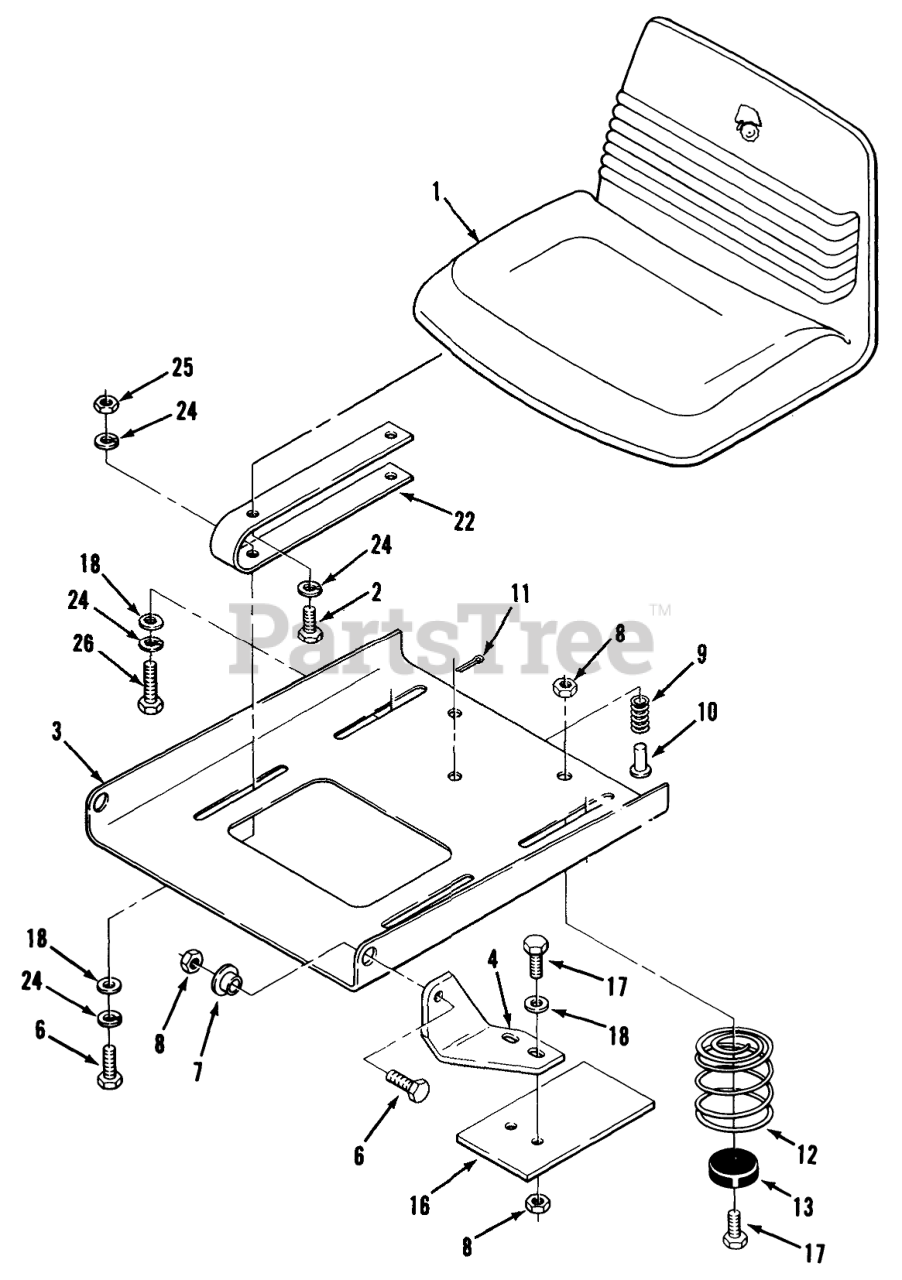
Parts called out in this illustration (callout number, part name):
1	Seat
2	Bolt
3	PLATE-SEAT PIVOT B
4	Bracket-Pivot RH
6	HHCS
7	BUSHING
8	Nut
9	SPRING-SEAT SWITCH
11	Cotter Pin
12	SPRING
13	BUMPER
16	PLATE R
17	Bolt
18	WASHER 5/16 SAE
22	SPRING-SEAT B
24	Lockwasher
25	Nut
26	Bolt
